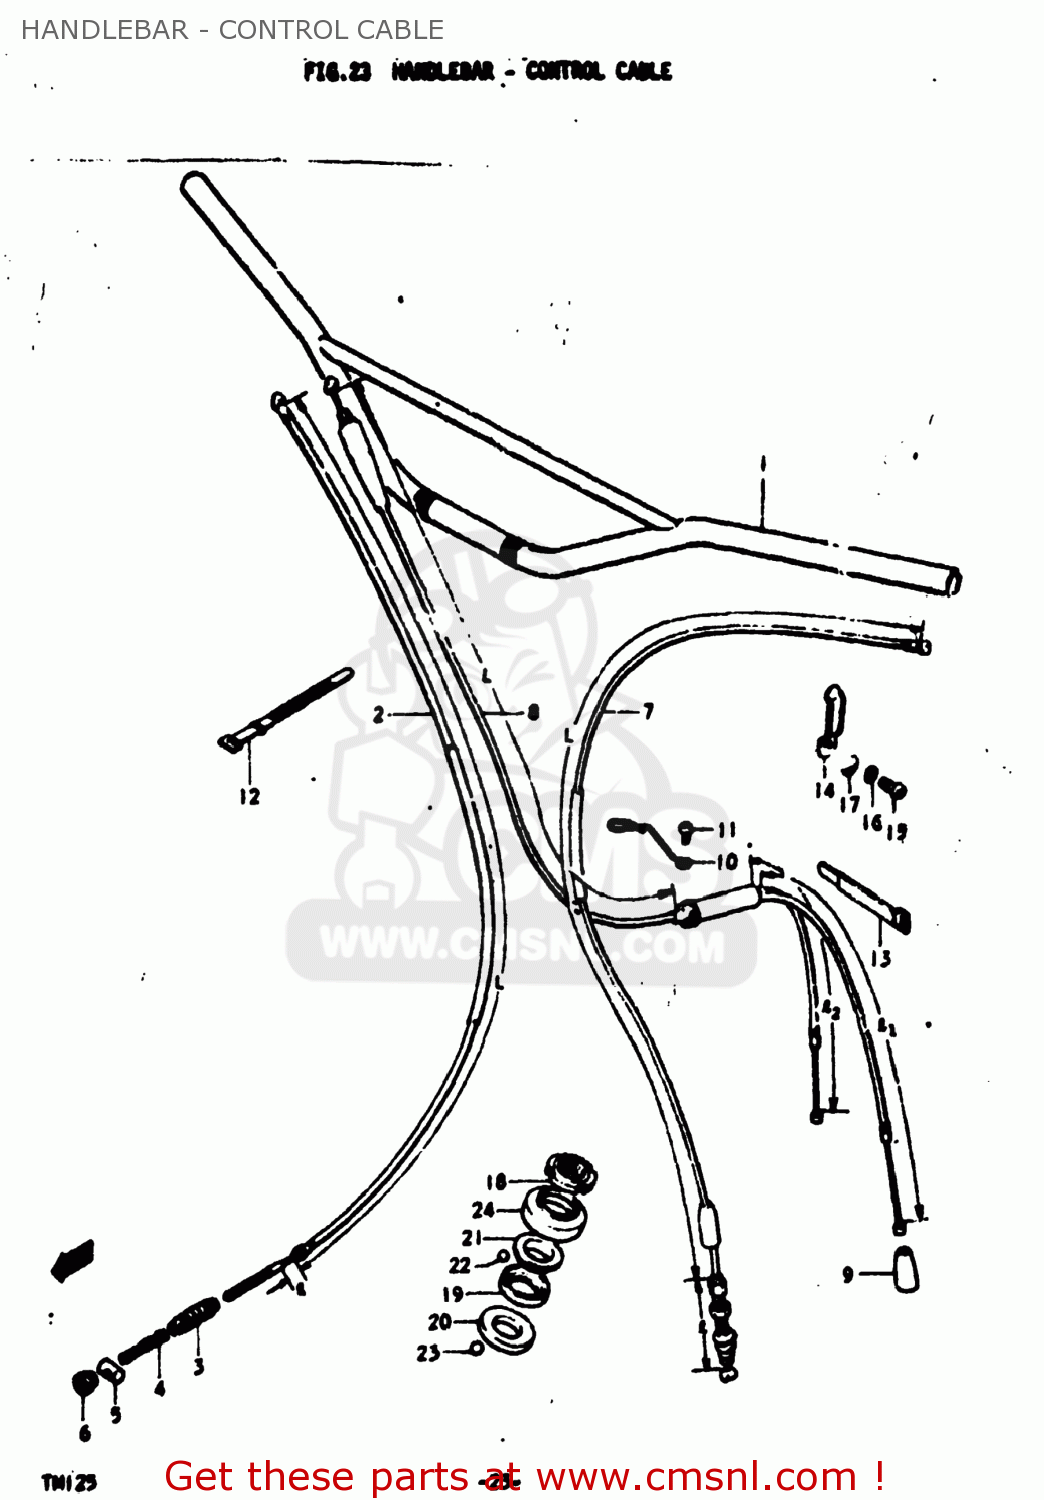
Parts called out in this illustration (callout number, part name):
1	HANDLEBAR
2	CABLE,FRONT BRAKE
3	SEAL,DUST(7X16X75)
4	SPRING
5	PIN,10X19
6	NUT
7	CABLE ASSEMBLY,CLUTCH
8	CABLE ASSEMBLY,THROTTLE
9	SEAL,DUST(7X18X30)
10	GUIDE,CABLE
11	SCREW
12	CLAMP
13	CLAMP L:110
14	CLAMP
15	SCREW
16	LOCK WASHER
17	WASHER
18	NUT,STEERING STEM(25X44X10)
19	RACE,STEERING INNER UPR
20	LACE,STEERING INNER LWR
21	RACE,STEERING OUTER UPR
22	BALL
23	BALL
24	DUST SEAL,STEERING UPR
